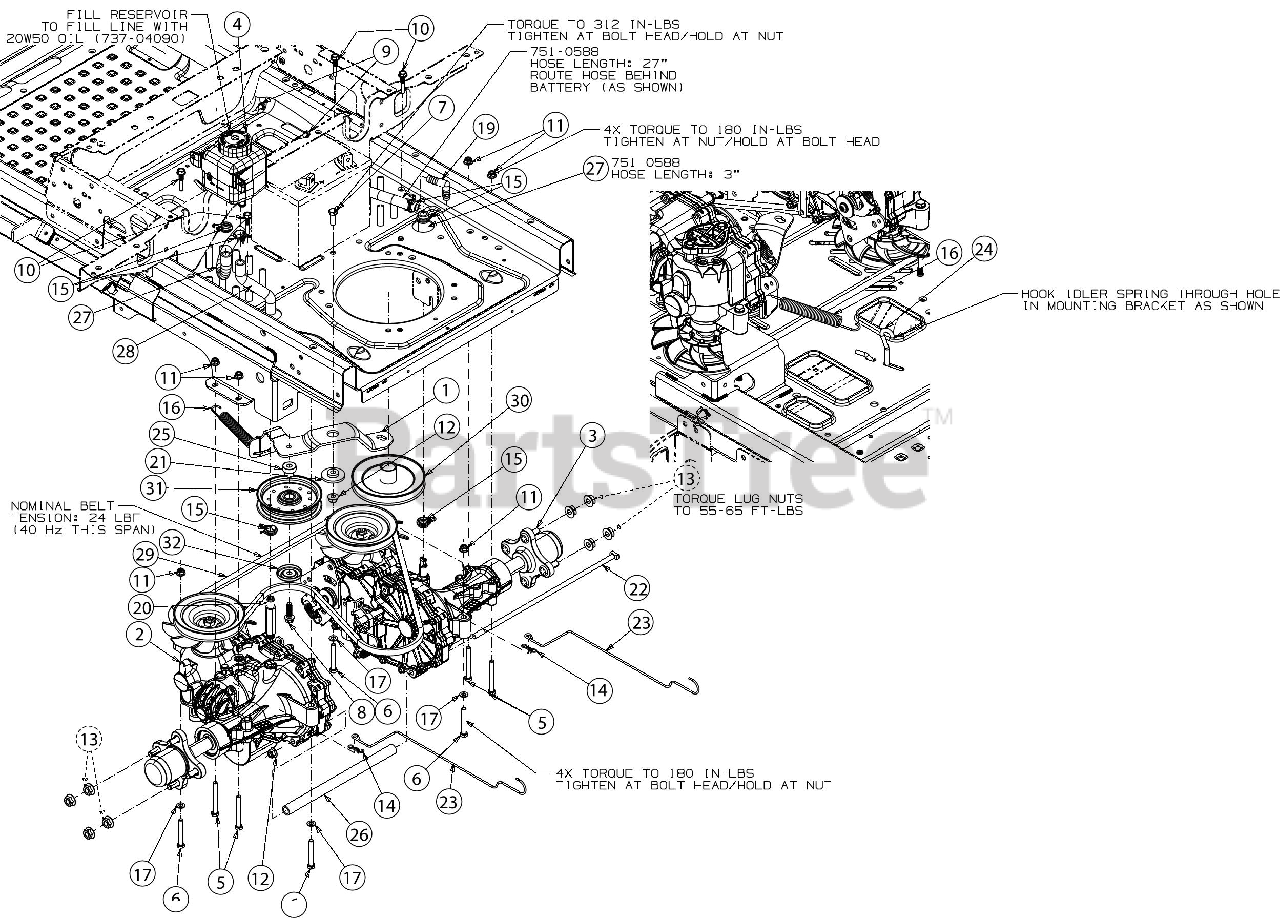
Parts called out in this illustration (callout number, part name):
1	IDLER BRACKET ASSEMBLY
2	HYDRO TRANSMISSION ASSEMBLY (LH)
3	HYDRO TRANSMISSION ASSEMBLY (RH)
4	HYDRAULIC TANK
5	HEX SCREW 5/16-18 x 2.75
6	HEX SCREW 5/16-18 x 2.25 GR5
7	SCREW 3/8-16 x 1 GR5
8	SCREW 3/8-16 X1.250
9	SCREW 1/4-20X.625
10	BELT KEEPER ROD .25 x 1.585
11	FLANGE LOCK NUT 5/16-18
13	HEX FLANGE NUT 7/16-14
14	BOW TIE COTTER PIN 1/4-5/16
15	FUEL HOSE CLAMP
16	EXTENTION SRING .75 DIA. x 6.85
17	FLAT WASHER
19	90 DEGREE NYLON FITTING
20	EXTENSION FITTING 9/16-18
21	SHOULDER SPACER
22	SUPPORT TUBE ROD
23	HYDRO BYPASS ROD
24	IDLER SPRING HOOK
25	SHOULDER SPACER
26	TRANSMISSION SPACER .75OD x 11.31
27	FUEL LINE 1/2" ID
28	TRANSMISSION EXPANSION HOSE
29	TRANSMISSION DRIVE BELT A x 67
30	ELECTRIC PTO PULLEY
31	IDLER PULLEY 4.25 DIA
32	IDLER PULLEY CAP
